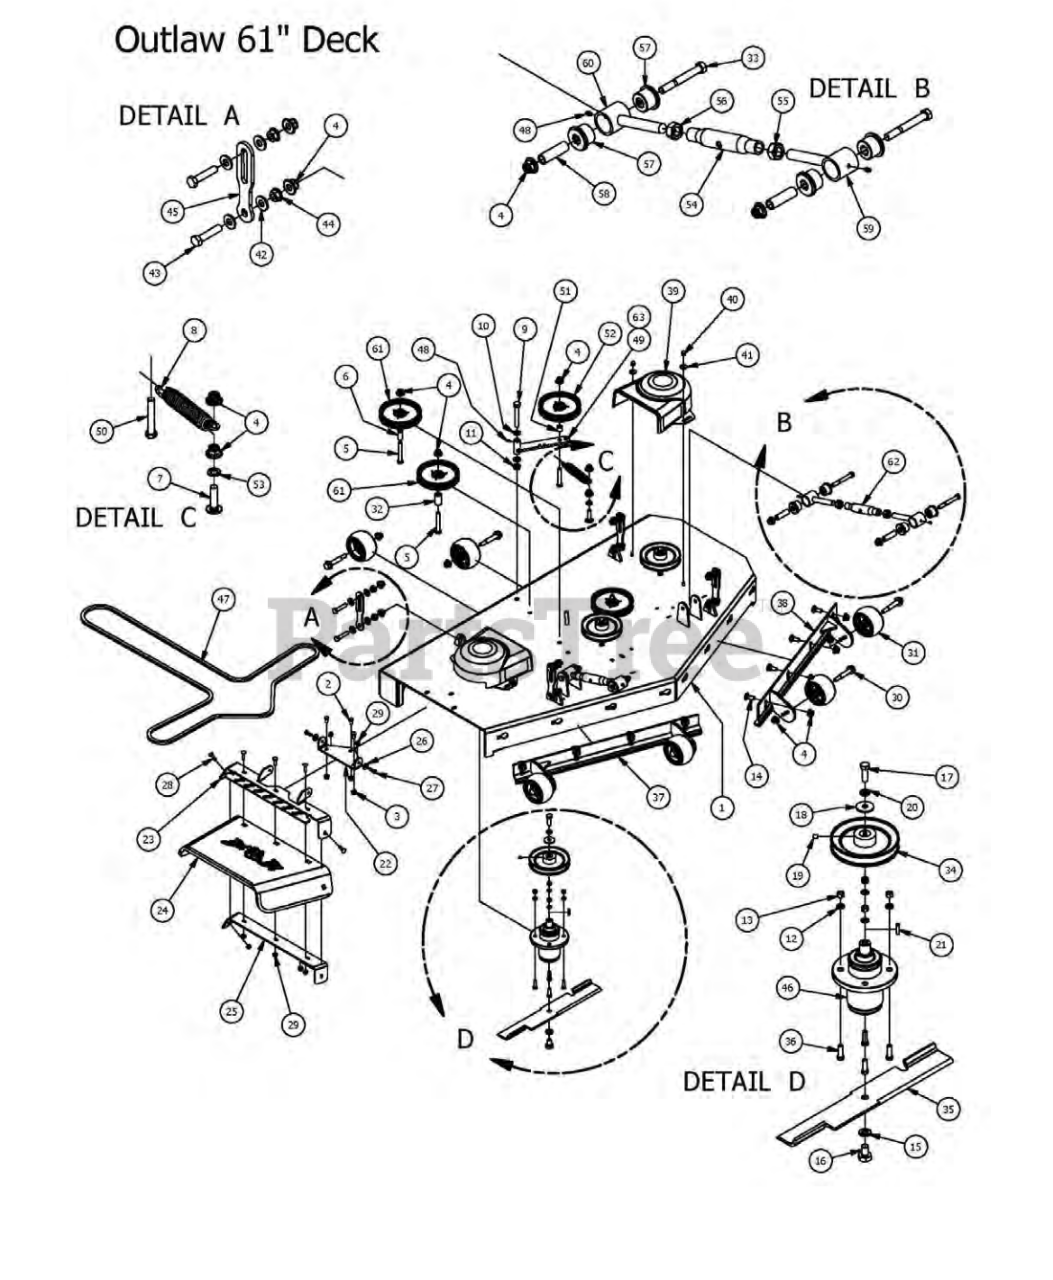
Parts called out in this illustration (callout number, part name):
1	2015 61 Deck
2	3/8" x 3/4" Hex Bolt
3	3/8 Flange Nut
4	1/2-13 Nylon Flange Nut
5	1/2 x 3 1/2 Flange Bolt Grade 8
6	502 ID X.750 OD X 1.500 Long Spacer
7	1/2 x 2" Carnage Bolt
8	2015 Deck Idler Spring Outlaws
9	5/8" x 4" Hex Bolt
10	630 ID Plastic Washer
11	5/8-11 Nylon Insert Jam Half Nut
12	3/8 Lockwasher Zinc
13	3/8-16 Hex Nuts Zinc
14	1/2" x 11/4 Carriage Bolt
15	5/8" Lock Washer
16	5/8" x 11/2" Grade 8 Hex Bolt (Fine)
17	1/2-20 x 1 1/2 Grade 5 Fine Thread Bolt
18	1/2 Belleville Washer
19	5/16 Set Screw
20	1/2" Lock Washer
21	1/4" x 1" Key
22	Discharge Chute Hanger (deck mounted)
23	60" Discharge Chute Upper Hanger
24	Rubber Discharge Chute
25	60" Discharge Lower Bracket
26	360 ID Plastic Washer
27	5/16" x 1" Bolt
28	5/16" 1 1/4" Carriage Bolt
29	5/16" Nylock Flange Nut Zinc
30	Deck Wheel Balt
31	Anti-Scalp Rollers
32	1 3/4" Pulley Spacer
33	1/2" x 4" Bolt (Grade 8)
34	6 1/4 Drive Pulley
35	61 inch Fusion Blade
36	3/8" x 11/4" Hex Bolt
37	61 Deck Adustable Front (Right)
38	61 Deck Adustable Front (Left)
39	Pulley Cover
40	Acorn nut-pulley Cover
41	360 ID Plastic Washer-Black
42	505 Nylon Spacer
43	1/2-13X 2-1/4 GR Hex Bolts
44	1/2" Flange Nut
45	Deck Hanging Tab
46	OUTLAW SPINDLE ASSEMBLY
47	B226 Belt for 1100cc Diesel
48	1/4" Press in Grease Fitting
49	Deck Idler
50	1/2-13 x GR 5 Hex Bolt Zinc
51	Spacer 3/4 OD x 1/2 ID x 3/4 Length
52	5-3/4 Idler Pulley-Don Dye
53	517 Square Hole Round Washer
54	2015 Outlaw Toplink Body
55	3/4-10 Left-Handed Hex Nuts Zinc
56	3/4-10 Hex Nuts Zinc
59	Turn Left-Handed
60	Right-Handed End
61	5-3/4 Idler Pulley-Capitol Stampings
62	Tumbuckle Assembly
63	Deck Idler Assembly - Includes parts: 4,49,50,51,52
